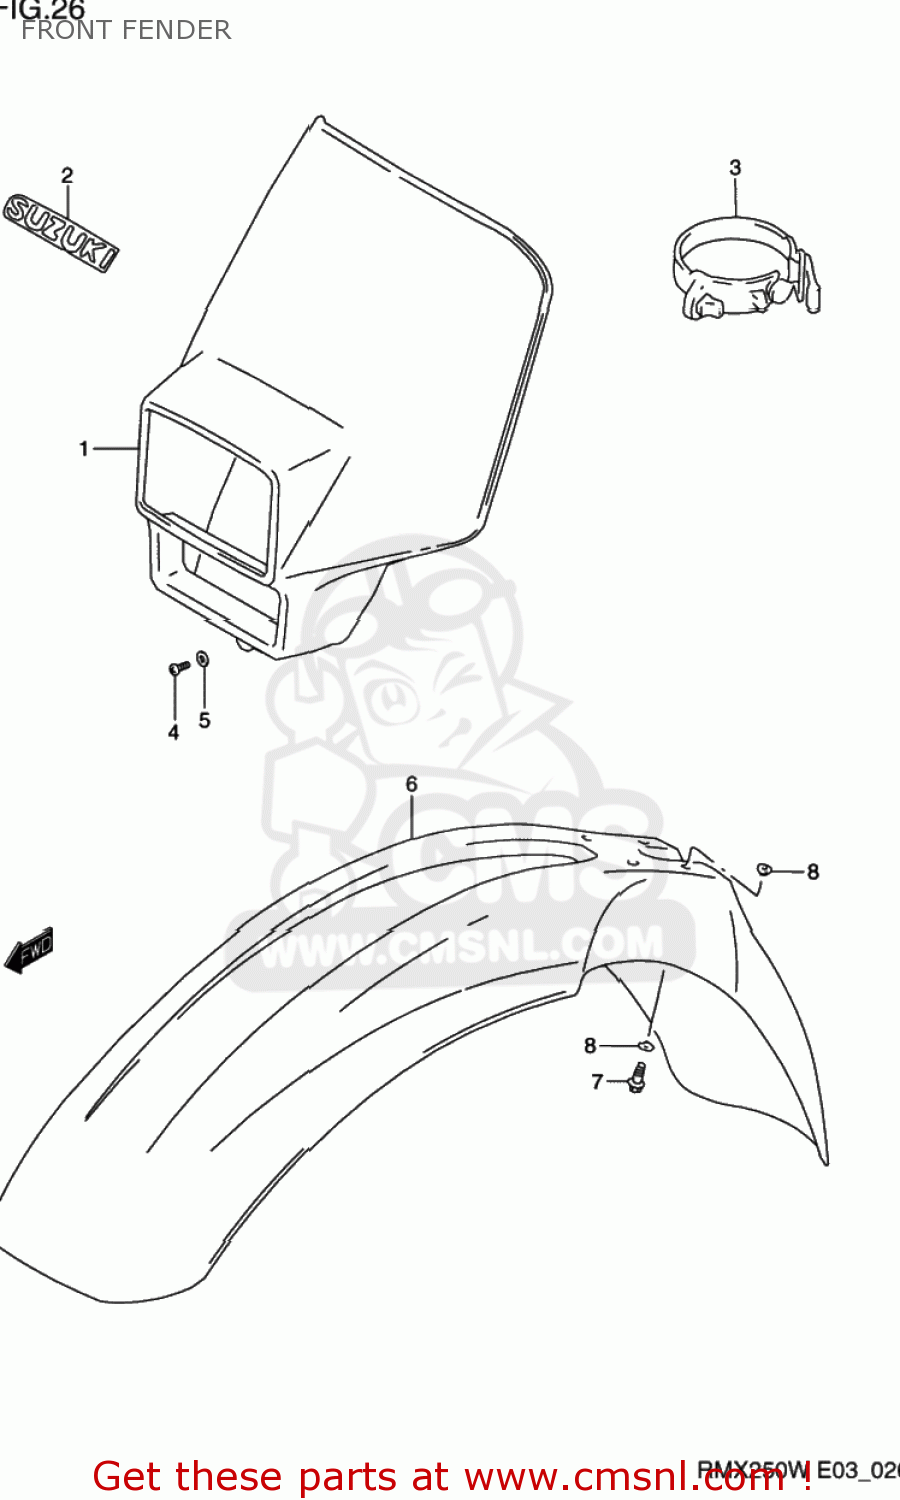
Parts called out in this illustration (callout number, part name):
1	COVER,HEADLAMP
2	EMBLEM,HEADLAMP COVER
3	BAND,HEADLAMP COVER
4	SCREW
5	WASHER
6	FENDER,FRONT (YELLOW)
7	BOLT
8	WASHER
